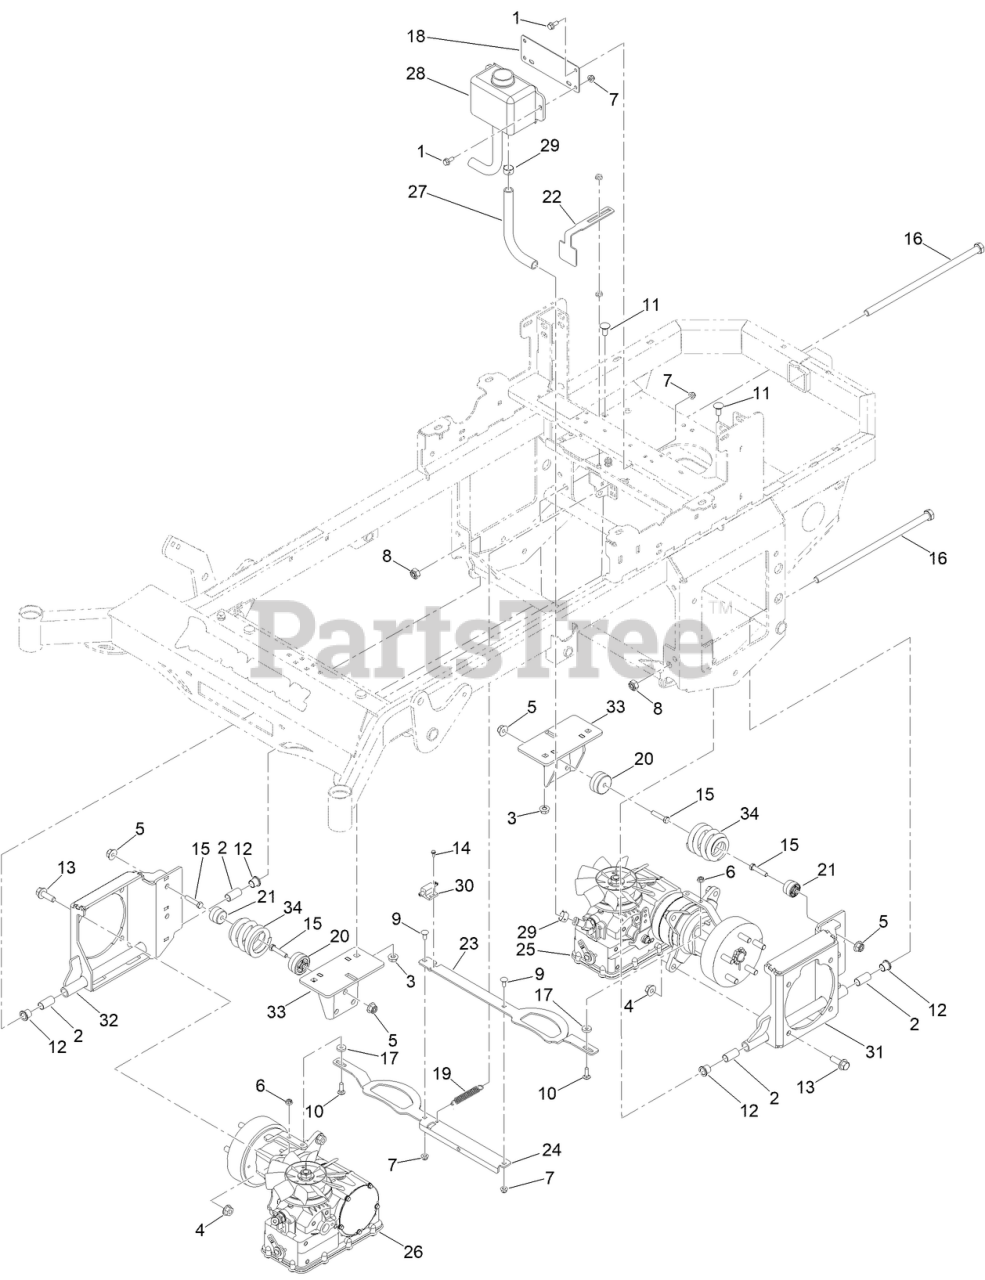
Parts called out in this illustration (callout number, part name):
1	SCREW-HHF
2	.625 ID X .750 OD X 1.500IN OI BUSHING
3	7/16-14 HEX FLANGE NUT W/SERR ZINC
4	NUT-HHF
5	3/8-16 NYLON INSERT FLANGE L/NUT YZ
6	5/16-18 NYLON INSERT FLANGE L/NUT ZC
7	NUT-HF, NI
8	5/8-11 NYLON INSERT FLANGE L/NUT ZINC
9	BOLT-CARR
10	BOLT-CARR
11	SCREW-CARR
12	BUSHING-FLANGE
13	SCREW-HHF
14	8-32 X 1/2 IND. HWH SLOT TYPE F TCS ZINC
15	3/8-16 X 1-3/4 HEX C/S GR 2 ZINC
16	5/8-11 X 15IN HEX C/S GR 2 ZC 3IN THD L
17	.312 ID X .875OD X .1875 THK F/W NYL
18	MWR HYDRAULIC RESERVOIR MTG PLATE BLACK
19	MWR BRAKE PEDAL RELEASE SPRING
20	SUSP SPRING INSIDE GUIDE
21	SUSP SPRING OUTSIDE GUIDE
22	STAND TRANS BRAKE INTERLOCK BRKT PAINT
23	2022 XD PARK BRAKE BRKT G16 LT GREY
24	2022 XD PARK BRAKE BRKT G16 RT GREY
25	HTG16 LT SIDE TRANSM W/CONTROL ORIFICE
26	HTG16 PARKER RT SD TRANS W/CNTRL ORIFICE
27	MWR 5/8IN HYDRAULIC HOSE, 1FT
28	HYDRAULIC FLUID RESERVOIR
29	22MM HOSE CLAMP (CTB-22ST-FK)
30	NO PLUNGER LIMIT SWITCH
31	XD LT RR SUSP ASSY PAINTED
32	XD RT RR SUSP ASSY PAINTED
33	MWR SUSP FRAME BRKT ASSY PAINT
34	SRT RR SUSP SPRING
